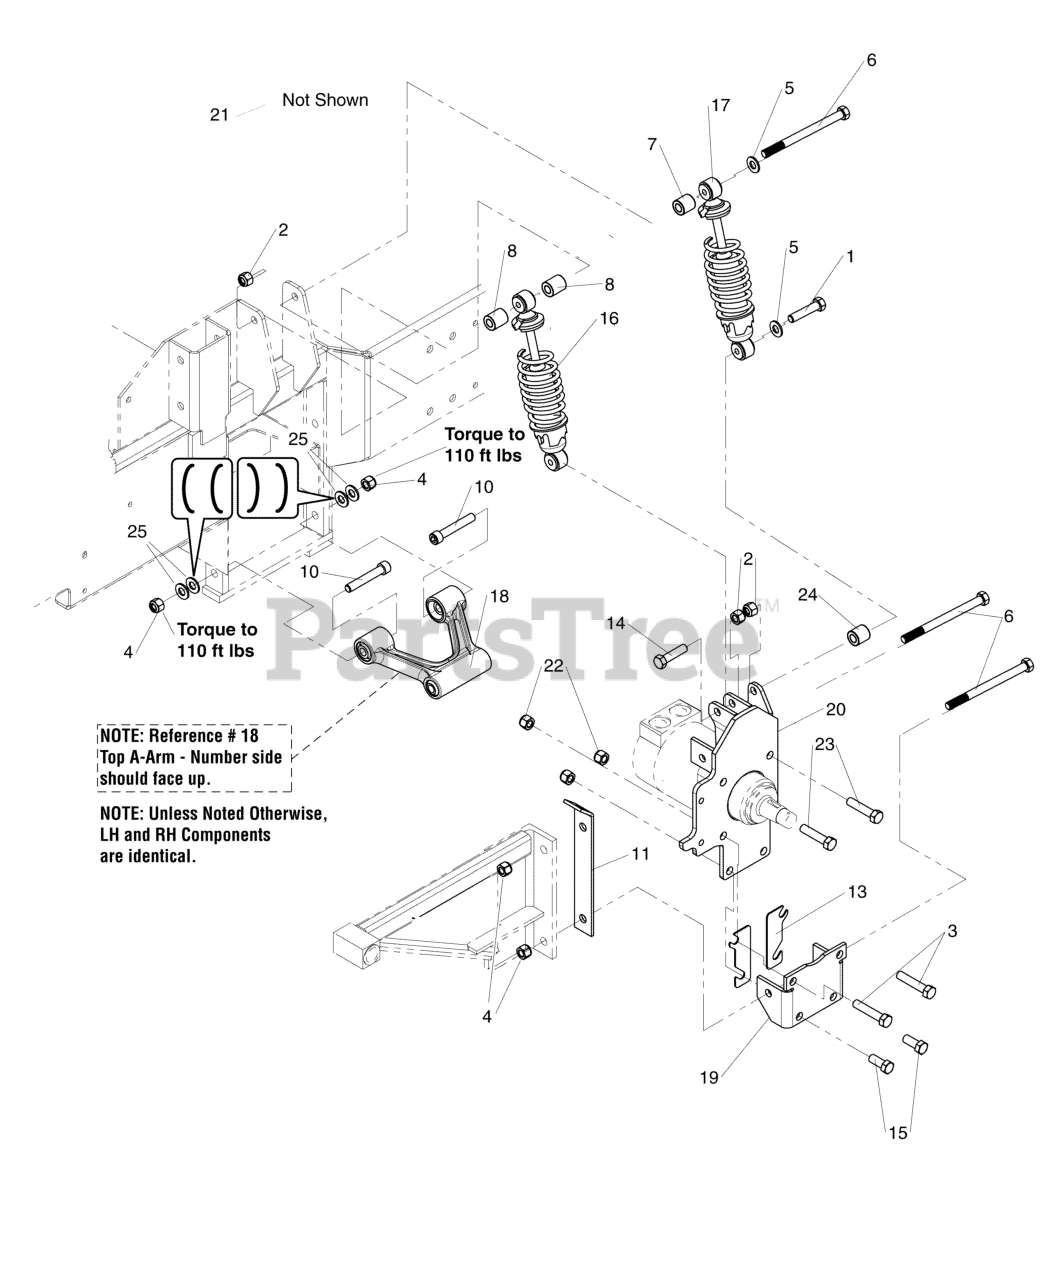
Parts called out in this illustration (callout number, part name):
1	BOLT, 1/2-13 X 2-1/4" GD5 CZ
2	NUT, 1/2-13 Hex Side Lock
3	BOLT, 1/2-20 X 3" GD5 YZ
4	NUT, 1/2-13 HEX NYLOCK FLANGE GR8, YZ
5	WASHER, 1/2 SAE
6	BOLT, 1/2-13 X 6-1/2" GD8 YZ
7	SPACER, .52 x 1.00 x 1.00
8	SPACER, .52 X 1.00 X 1.15
10	BOLT, 1/2-13 X 3-1/4" ALLEN HEAD
11	WELD, BRACKET, BRAKE CABLE, RH
13	SHIM, CAMBER - PLATED
14	BOLT, 1/2-13 X 2" GD5 CZ
15	BOLT, 1/2-20 X 1-3/4" GD8 CZ
16	SHOCK, REAR, IS4500
17	SHOCK/SPRING ASSEMBLY, IS5000 (2006)
18	ASSM, A-ARM WITH BEARINGS
20	WELD, MOTOR MOUNT, LH - RED
22	NUT, Hex, Nylon Lock, 1/2-20
23	BOLT, 1/2-20 X 2-1/2" GD5 CZ
24	SPACER, .52 X 1.00 X .38, CZ
25	BELLEVILLE WASHER, 1.259 X .512 X .138 YZ
